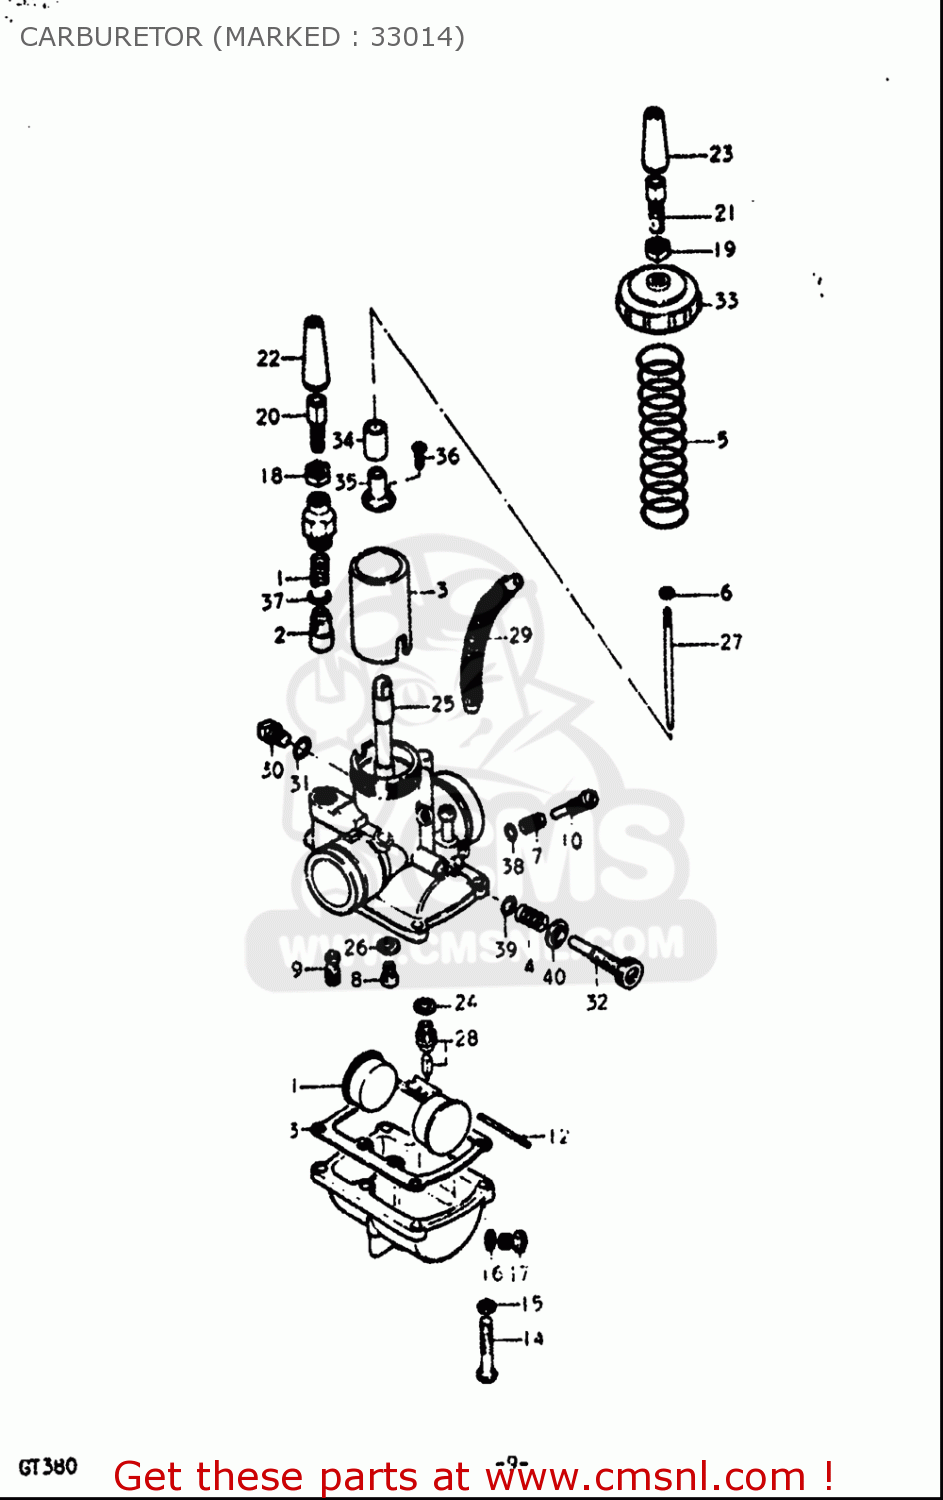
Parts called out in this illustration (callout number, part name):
1	SPRING
2	PLUNGER,STARTER
4	SPRING
6	CLIP
7	SPRING
8	JET,MAIN
9	JET,PILOT(22.5)
12	PIN,FLOAT
13	GASKET,FLOAT CAHMBER (NAS)
14	SCREW 4X16
15	WASHER,LOCK
16	GASKET,DRAIN,PLUG (NAS)
18	NUT
20	ADJUSTER,CABLE
21	ADJUSTER,CABLE
22	CAP
23	CAP,CABLE ADJUSTER
24	GASKET,VALVE SEAT (NAS)
26	WASHER
27	NEEDLE,JET
28	VALVE ASSY,NEEDLE
30	BOLT
31	GASKET,THRO VALVE INSPECTION (NAS)
35	CONNECTOR
36	SCREW
38	O RING
39	O RING
40	COVER
